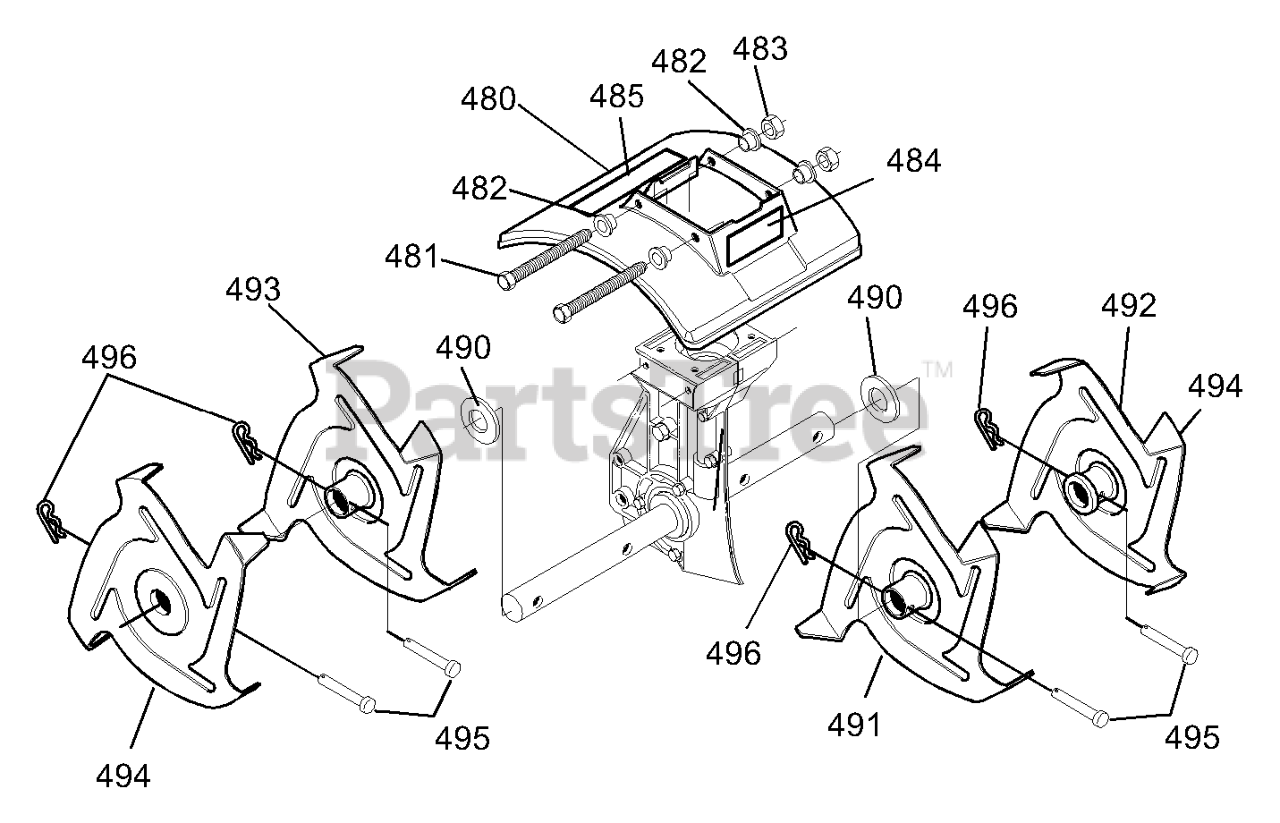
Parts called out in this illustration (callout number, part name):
480	Shield, Tine
481	Screw, 1/4-20x5.50
482	Spacer, Flange
483	Nut, 1/4-20
484	Decal, Murray
485	Decal, Caution
490	Washer, Felt
491	Tine Assy. Inner LH
492	Tine Assy. Outer LH
493	Tine Assy. Inner RH
494	Tine Assy. Outer RH
495	Clevis Pin
496	Hair Pin
